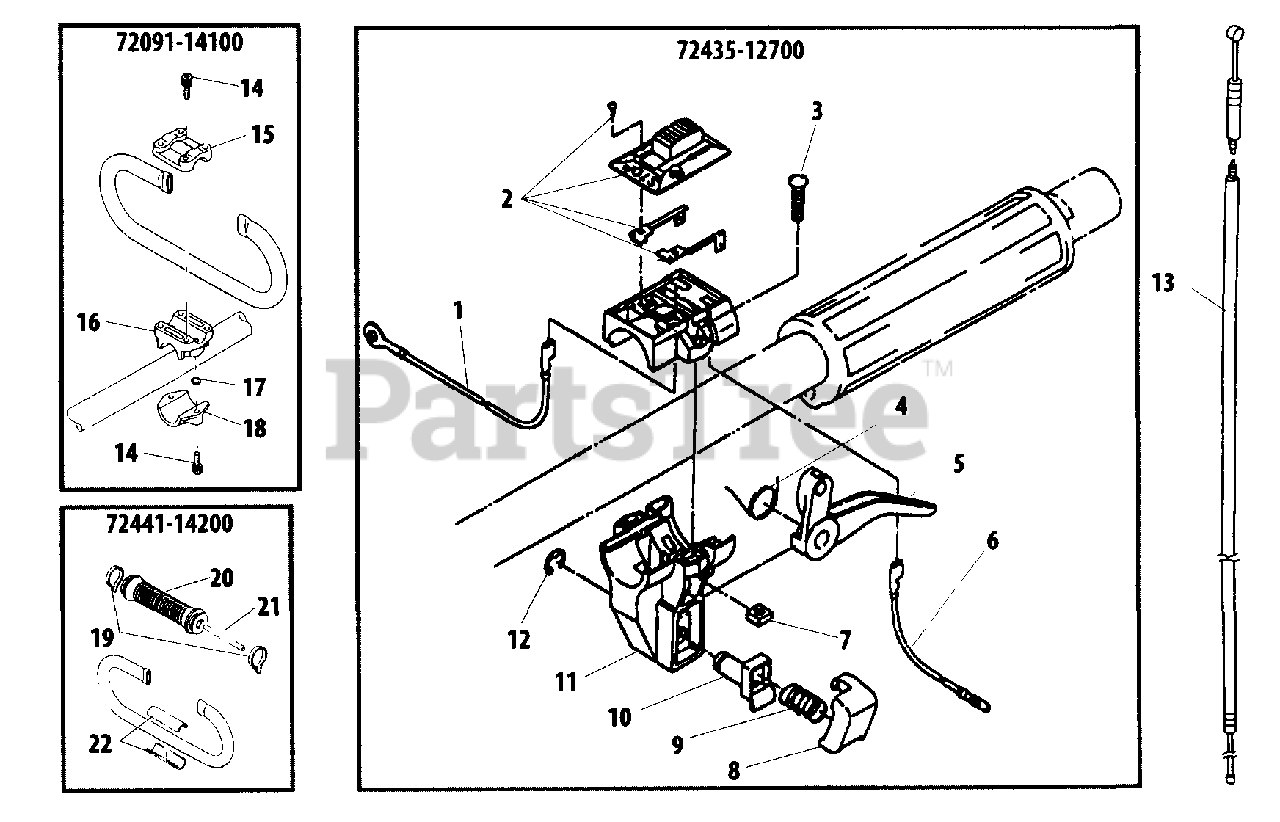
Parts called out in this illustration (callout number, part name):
1	LEAD - GROUND
2	SWITCH ASSY
3	SCREW - 5X20
4	SPRING, TRIGGER
5	LEVER, THROTTLE
6	LEAD - IGNITION
7	NUT
8	BUTTON, THROTTLE LEVER
9	SPRING
10	SHAFT
11	BODY
12	RING, RETAINING
13	CABLE, THROTTLE
14	SCREW - 5X25
15	CAP - UPPER
16	BRACKET, HANDLE
17	WASHER - 5
18	CAP - LOWER
19	CLAMP
20	GRIP, HANDLE
21	CORE, GRIP
22	SPACER, HANDLE
72091-14100	HANDLE BRACKET KIT
72435-12700	THROTTLE LEVER ASSY
72441-14200	HANDLE ASSY
